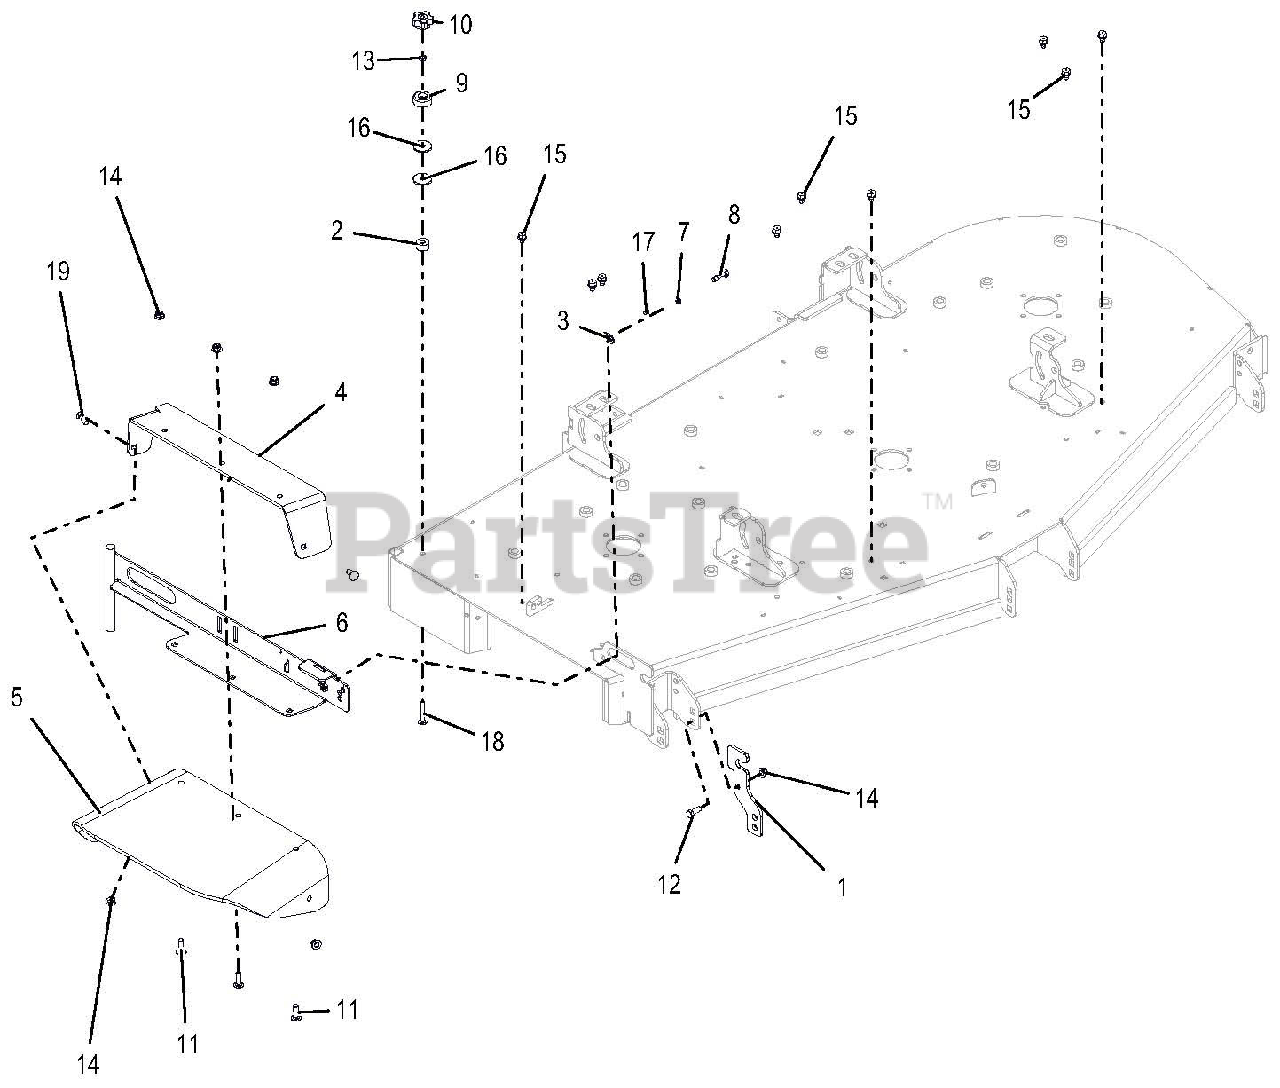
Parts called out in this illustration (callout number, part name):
1	CHUTE STORAGE BRACKET - RED
2	SPACER .390X1.000X.562
3	KEEPER, BOLT
4	DISCH CHUTE SUPPORT W/DECAL
5	CHUTE, RUBBER DISCHARGE
6	WLDMT, 72" DISCH CHUTE MTG-CE
7	@WSHR-LK-EXT.391X.628X.036YWZC
8	BLT-HEX .38-16X1.25 GR5 CAP .37
9	BUMPER,RECESSED1.50X.63 W/.31
10	KNOB-CLAMPING, .312-18 NYLOC
11	@BLT-RDHDSQNK .38-16X1.25 G5YZ
12	@BLT-HEX .38-16X1.00 GR5 YWZC
13	@NUT-LK-CTR .31-18 YWZC
14	@NUT-LK-NYL-FLG .38-16 YWZC
15	@SCR-TAP .38-16X.50 HWH TR YWZ
16	WSHR-FL-STL .380X1.50X.125YWZC
17	RVT-POP .187x.250 (#64) YWZC
18	BLT-RDHDSQNKFT .31-18X2.0 G5YZ
19	@BLT-RDHDSQNK .38-16X1.00 G5YZ
